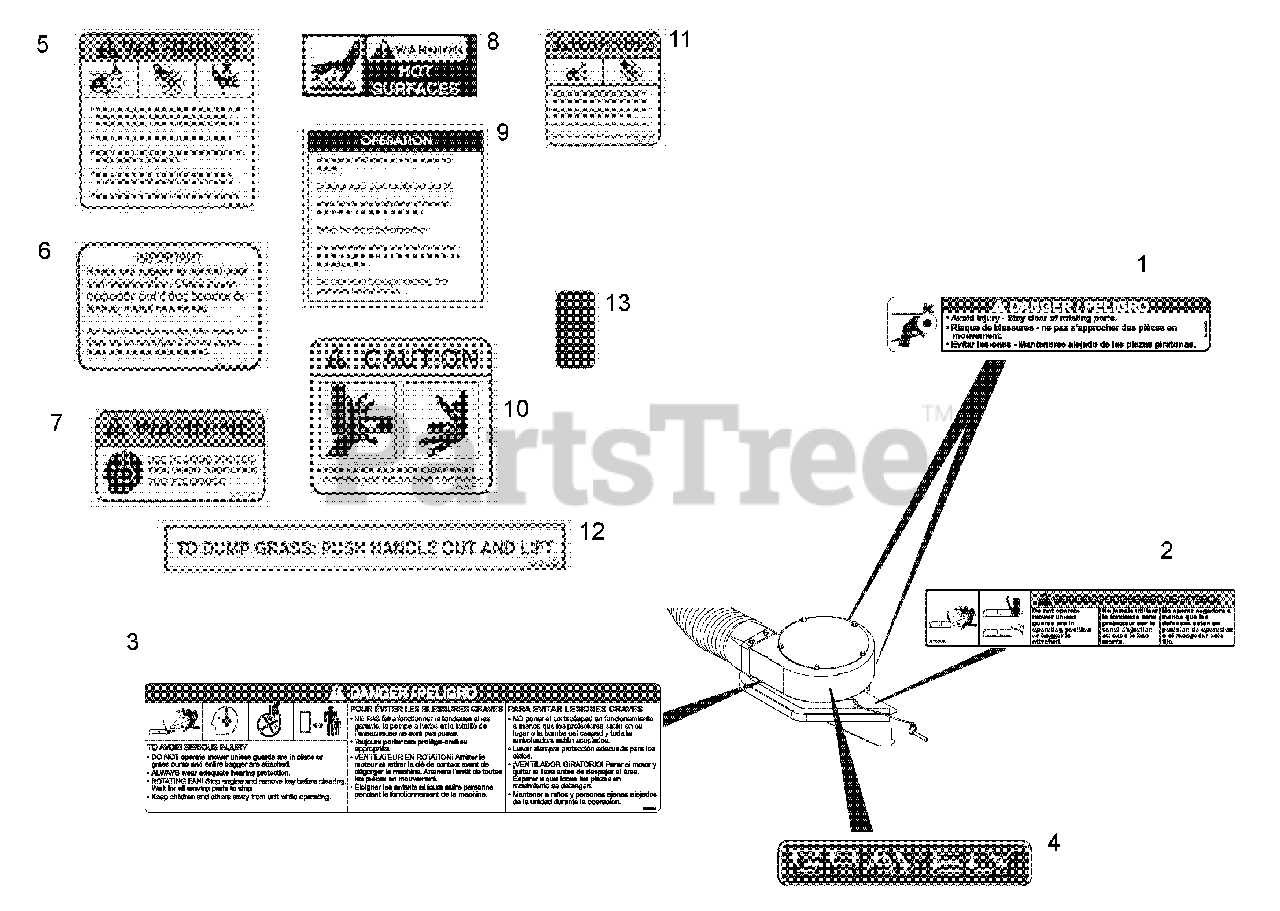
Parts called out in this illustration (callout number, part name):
1	Decal, Danger
2	Decal, Warning
3	Decal-Caution, Grass Pump
4	Decal, Gravely
5	Decal, Warning
6	Decal, Important
7	Decal, Hearing Warning
8	Decal, Hot Surface Warning
9	Decal, Operation
10	Decal, Pinch Point Caution
11	Decal, Rotating Parts Warning
12	Decal, Lift Handle Instruction
13	Decal, Reflective
